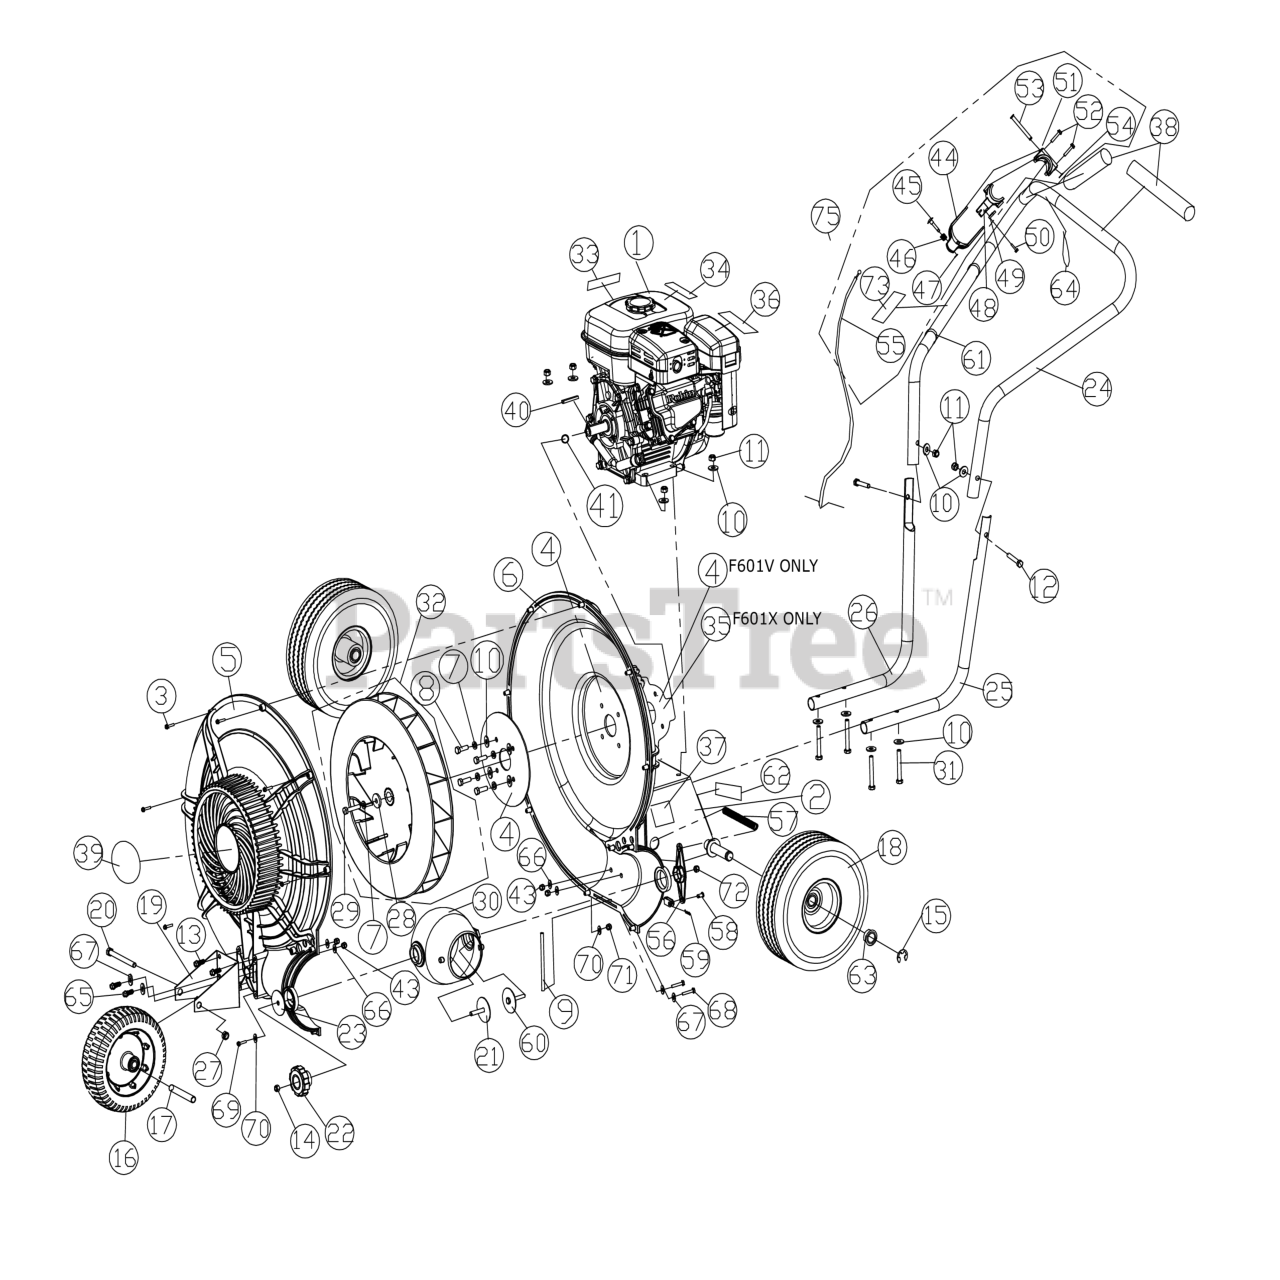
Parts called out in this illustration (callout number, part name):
1	ENGINE 5.5 B&S VANGUARD
2	BASE ENGINE SMALL FRAME WA SERVICE
3	SCREW PLASTITE #8-16 X 3/4" HWH ZP
4	PLATE ENGINE FACE
5	HOUSING FRONT SMALL FRAME SERVICE
6	HOUSING BACK SMALL FRAME
7	WASHER LOCK 5/16 ST MED
8	SCREWCAP 5/16"-24 X 1" GR.8 ZP W/PATCH
9	ROD HAND STOP
10	WASHER 5/16" FLATWASHER Z/P
11	NUT LOCK 5/16"-18 HEX Z/P
12	SCREWCAP 5/16"-18X1 3/4" HCS ZP
13	SCREW PLASTITE 1/4-10 X 3/4 HWH ZP
14	NUT LOCK 5/16"-18 LT WT TH ZP
15	RING RETAINING "E" 3/4"
16	WHEEL 8" OD X 0.5" BEARING
17	SPACER 0.5" OD X 3.424
18	WHEEL ASSY PNEUMATIC
19	BRACKET FRONT WHEEL
20	SCREWCAP 3/8"-16X3 3/4"ZP
21	BOLT W/WASHER 5/16-18 X 1-1/2 WA
22	KNOB 5/16"-18 X 5/8" FLUTED
23	WASHER EXTENSION
24	HANDLE UPPER SMALL FRAME
25	HANDLE LOWER LH SMALL FRAME
26	HANDLE LOWER RH SMALL FRAME
27	NUT LOCK 3/8-16 LT WT THIN ZP
28	WASHER 1.125 OD X 0.344 ID X .25 THK ZP
29	SCREWCAP 5/16"-24X1 1/2" GR 8 ZP
30	DIRECTOR CONE 3.5"
31	SCREWCAP 5/16"-18X2 1/2" HCS ZP
32	IMPELLER ASSEMBLY
33	SEE: 100256
34	LABEL HOT ENGINE
36	LABEL SAFETY PROTECT READ MANUAL
37	LABEL DANGER FLYING DEBRIS
38	GRIP HANDLE 1" X 13" FOAM
39	LABEL SMALL FORCE GEN II
40	KEY 3/16" SQ X 1 3/4"
43	NUT LOCK 1/4"-20 HEX Z/P
44	LEVER DIVERTER
45	PIN LATCH DIVERTER
46	SPRING COMPRESSION 0.281 X 0.88
47	RING RETAINING 3/16" E-CLIP
48	SADDLE LOWER DIVERTER
49	PLATE LOCK DIVERTER
50	SCREW PLASTITE #10-14 X 1" HWH ZP
51	SADDLE UPPER DIVERTER
52	SCREW PLASTITE #6-19 X 5/8" HWH ZP
53	PIN PIVOT DIVERTER CONTROL
54	RING RETAINING 5/16"
55	CABLE DIVERTER SMALL FRAME
56	DIVERTER REMOTE ADAPTER
57	SPRING EXTENSION .468 X 5.25
58	PIN CLEVIS 1/4" X .75"
59	PIN CLIP HITCH 0.051 X 3/4"
60	ADAPTOR MOUNT WA
62	LABEL VIBRATION
63	FORCE WHEEL BEARING .751 ID
64	ELASTIC LOOP BLACK 5.5"
65	SCREWCAP 1/4"-20X1 1/4" HCS ZP
66	WASHER FLAT FENDER 5/16
67	WASHER 1/4"SAE9/32"X5/8"X1/16"
68	SCREWCAP 1/4"-20X1 1/2" HCS ZP
69	SCREWCAP #10-24 X 1 1/4" HWF ZP
70	WASHER #10SAE 7/32"X1/2"X1/16"
71	NUT LOCK LT #10-24 HEX
72	NUT LOCK 1/4- 20 2 WAY
73	FORCE AIM AND SHOOT LABEL
75	DIVERTER ASSY
